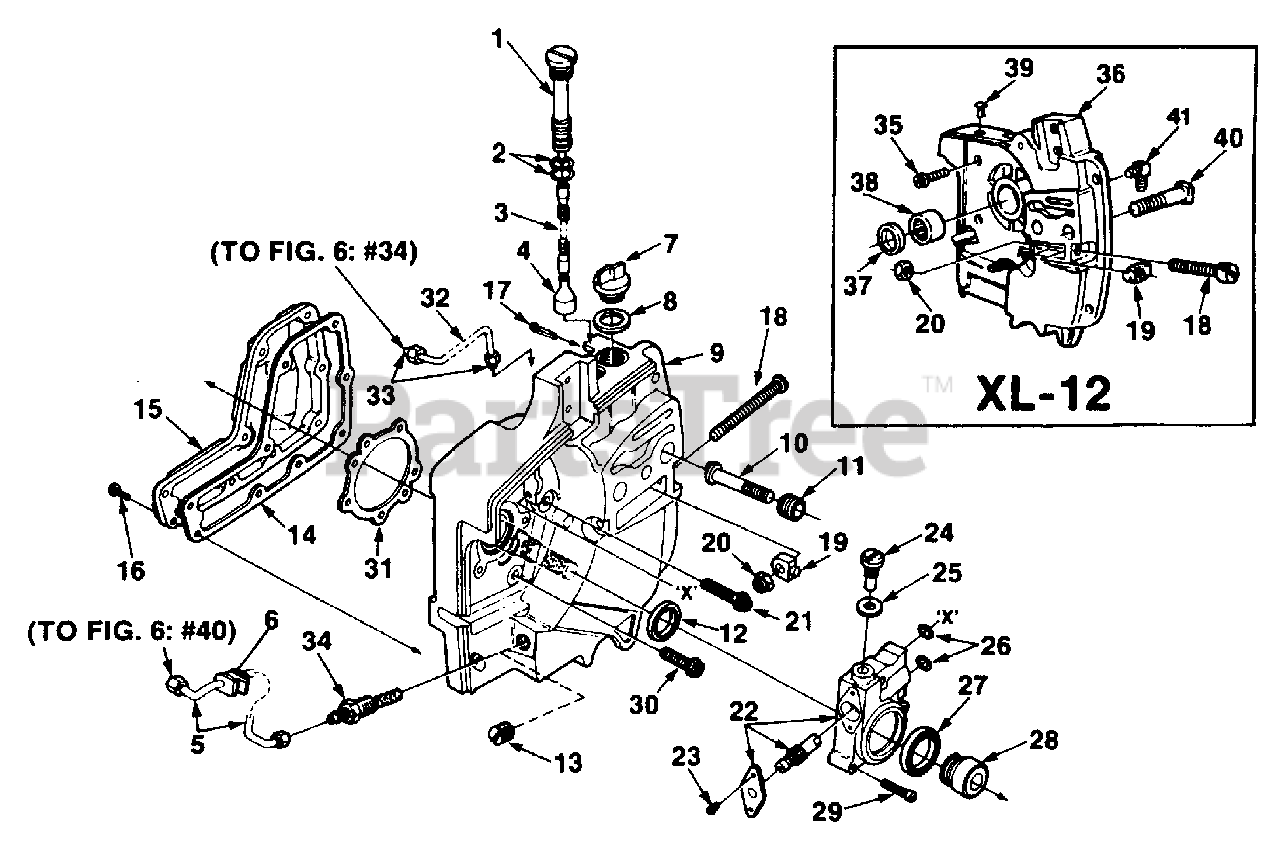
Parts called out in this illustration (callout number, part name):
1	TUBE- Oil line
2	"O" RING
3	TUBING- Rubber 2 1/4"
4	FILTER- Oil
5	LINE- Oil
6	GROMMET
7	CAP- Filler oil
9	DRIVECASE
10	STUD- Guide bar, 3/8
11	INSERT- Threaded
12	SEAL
14	GASKET- Oil reservoir
15	COVER- Oil reservoir
16	SCREW- Rd. 6-32 x 1/2
17	PIN- Cotter
18	SCREW- Guide bar adjusting
19	PIN- Bar adjusting
20	NUT- Lock, 1/4-20
21	SCREW- Hex 12-24 x 1
22	PUMP- Automatic oil
23	SCREW- Pan 4-40 x 1/4
24	SCREW- Cam
26	"O" RING
27	SEAL- Felt
29	SCREW- Fil. 8-32 x 3/4
30	SCREW- Hex 12-24 x 9/16
31	GASKET- Crankcase
32	LINE- Oil (Discharge)
33	SLEEVE- Compression
34	FILTER- Oil (Manual oil)
